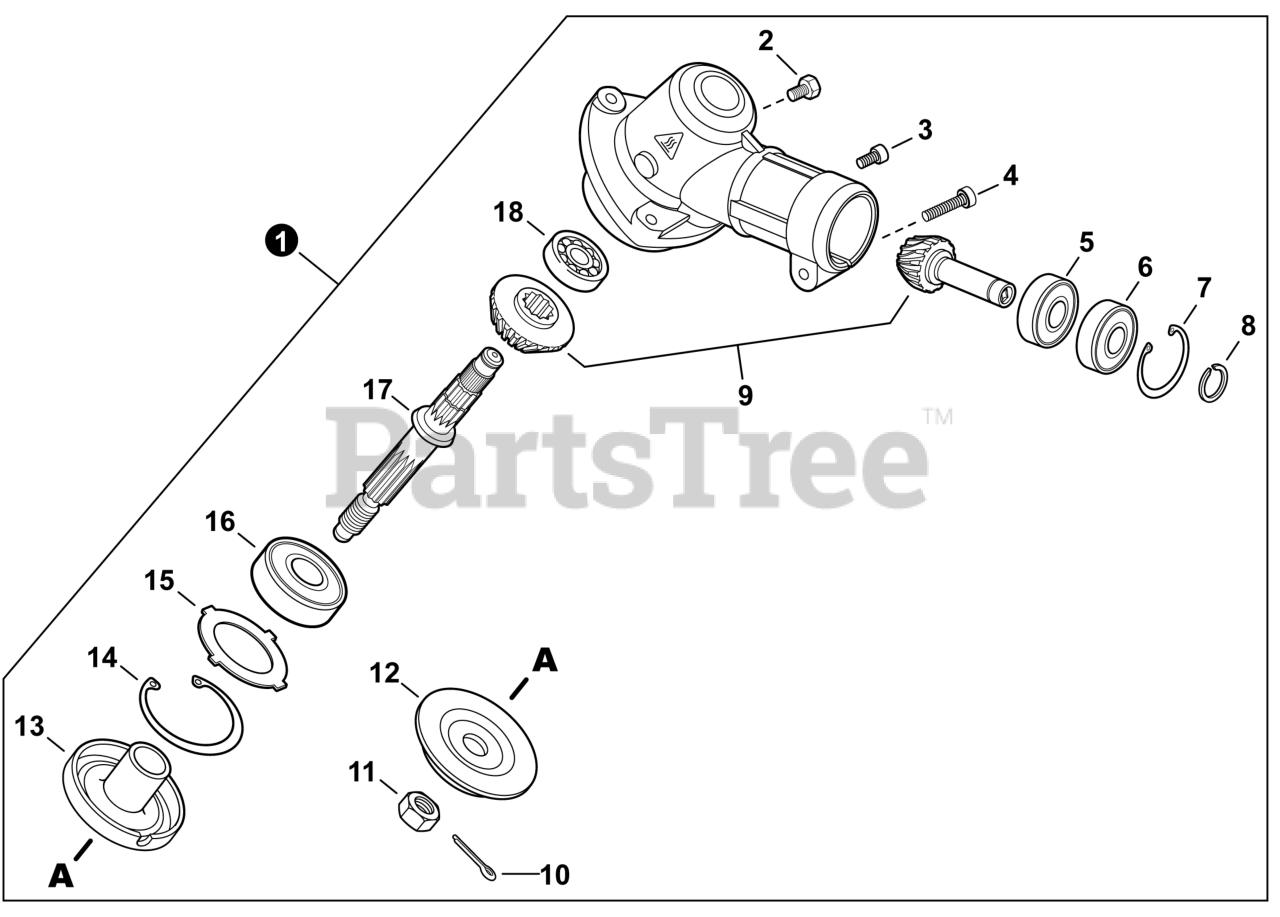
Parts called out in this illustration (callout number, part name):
1	GEAR CASE ASSY
2	BOLT M8x8
3	BOLT, TORX 5x12
4	BOLT, TORX 5x25
5	BEARING, BALL 609A
6	BEARING, BALL 609ZA
7	RING, SNAP 25
8	RING, SNAP 9
9	GEAR SET, BEVEL
10	PIN, COTTER 2x22
12	PLATE, ADAPTOR - LOWER
13	PLATE, ADAPTOR - UPPER
14	RING, SNAP 32
16	BEARING, BALL 6201
17	SHAFT, GEAR
18	BEARING, BALL 629A
